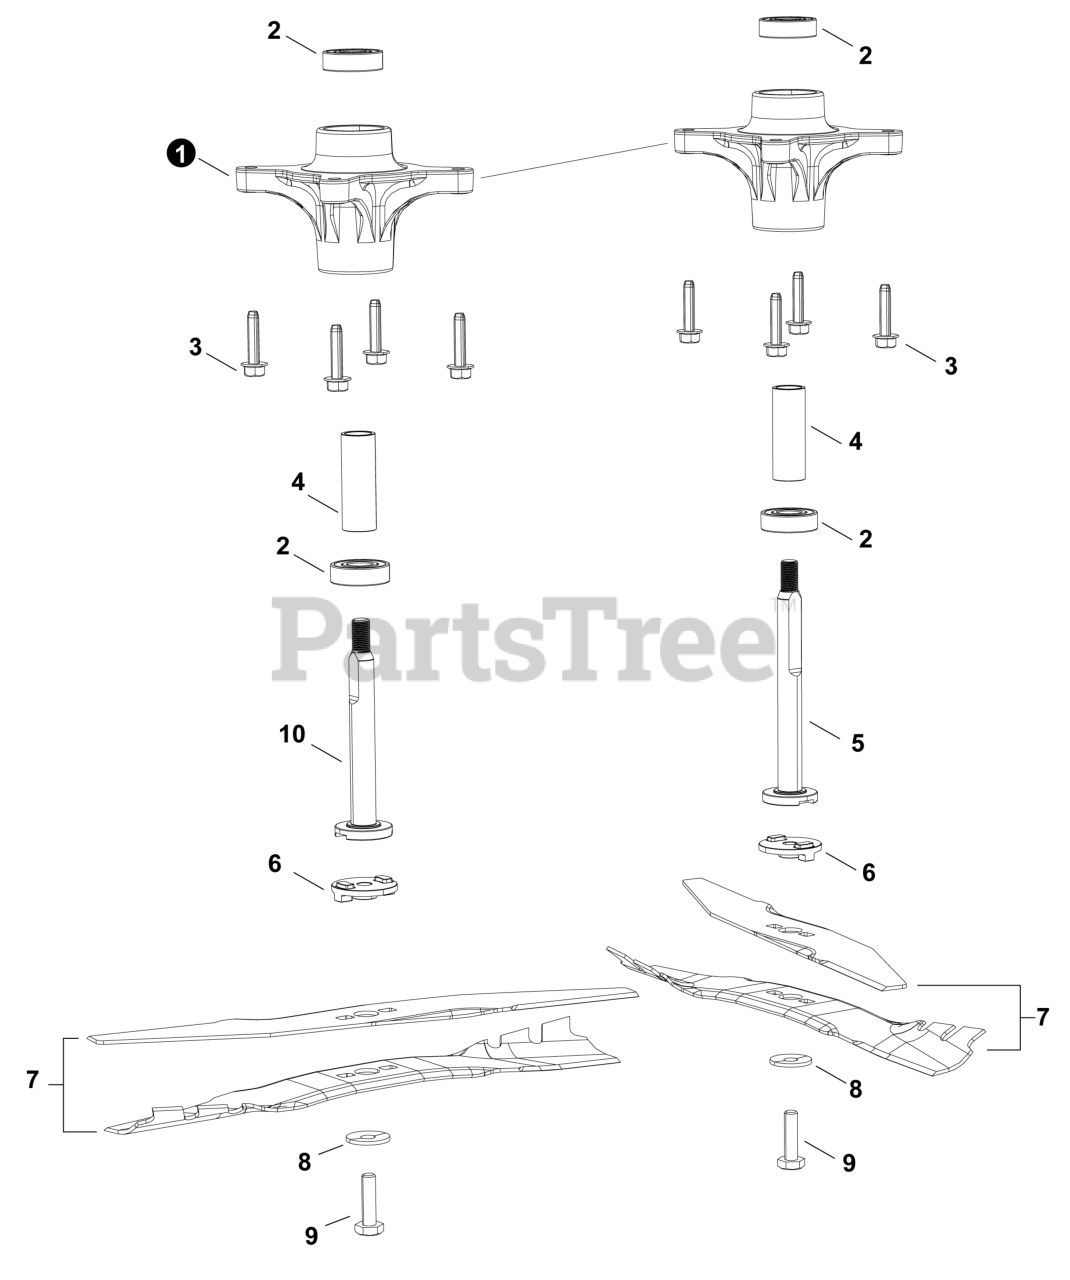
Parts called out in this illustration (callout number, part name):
1	HOUSING, SPINDLE
2	BEARING, SPINDLE
5	SHAFT, SPINDLE
6	ADAPTOR, BLADE
7	30" DUAL MOWER BLADE
9	BOLT, BLADE
10	SHAFT, SPINDLE
